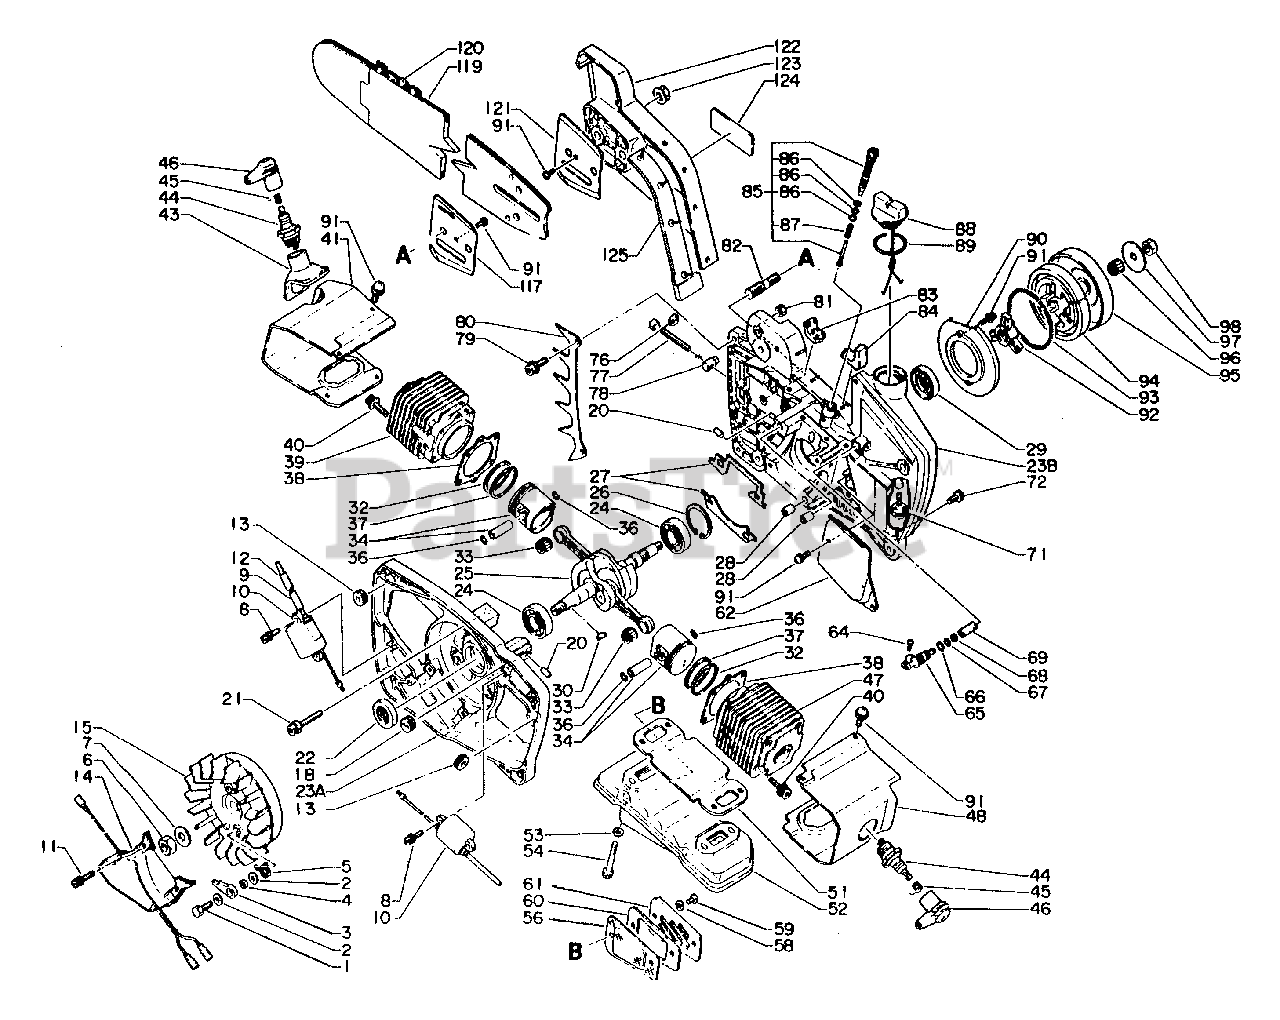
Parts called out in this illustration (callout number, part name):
1	BOLT - 5×16
2	WASHER 5.5×12×0.8
3	PAWL, STARTER
7	LOCKWASHER
8	BOLT 4×14
10	COIL, IGNITION
11	SCREW - 4×18
14	COIL, IGNITION
15	FLYWHEEL
20	PIN, LOCATING 4
21	BOLT M5×35
22	SEAL, OIL
23	CRANKCASE KIT
23A	CRANKCASE KIT
23B	CRANKCASE KIT
24	BEARING, BALL 6202
25	CRANKSHAFT ASSY
26	RING, SNAP 35
27	GASKET, CRANKCASE
28	PIN, DOWEL
29	SEAL, OIL 18
30	KEY, WOODRUFF
32	RING, PISTON
33	BEARING, NEEDLE 9
34	PISTON KIT
36	RING, RETAINING
37	RING, PISTON
38	GASKET, CYLINDER
39	CYLINDER, FRONT
40	BOLT 5×20
41	COVER, CYLINDER
43	CAP
44	SPARK PLUG - BPM7A
45	TERMINAL, SPARK PLUG
46	CAP, SPARK PLUG
47	CYLINDER - REAR
48	COVER, CYLINDER - RIGHT
51	GASKET, EXHAUST
52	MUFFLER
54	SCREW - 5×38
56	SCREEN, SPARK ARRESTER
58	WASHER, LOCK 5 MM
59	SCREW 5×8
60	GASKET, EXHAUST
61	COVER, MUFFLER
62	PLATE
64	SCREW 3×8
65	CONNECTOR
66	O-RING 7 MM
67	O-RING 6 MM
69	PIPE, FUEL 3×5×90 BLACK
71	FILTER, OIL
72	SCREW - 5×10
77	SCREW, ADJUSTER
78	TENSIONER, CHAIN
79	BOLT 5×14
80	SPIKE, BUMPER
81	NUT M5
82	STUD, GUIDE BAR
85	AUTO-OILER ASSY
88	CAP ASSY
89	O-RING 25 MM
90	PLATE
91	SCREW 4×10
92	HUB, CLUTCH
93	SPRING, CLUTCH
94	SHOE, CLUTCH
95	DRUM, CLUTCH - 3/8"
96	BEARING, NEEDLE
97	WASHER, CLUTCH
98	LOCKNUT
117	PLATE, GUIDE - INNER
119	GUIDE BAR -- 50RS50-3/8E
120	SAWING CHAIN - 72DP-72E
121	PLATE, GUIDE - OUTER
122	GUARD, SPROCKET
123	NUT, FLANGE M8×1.25
124	LABEL - ECHO
